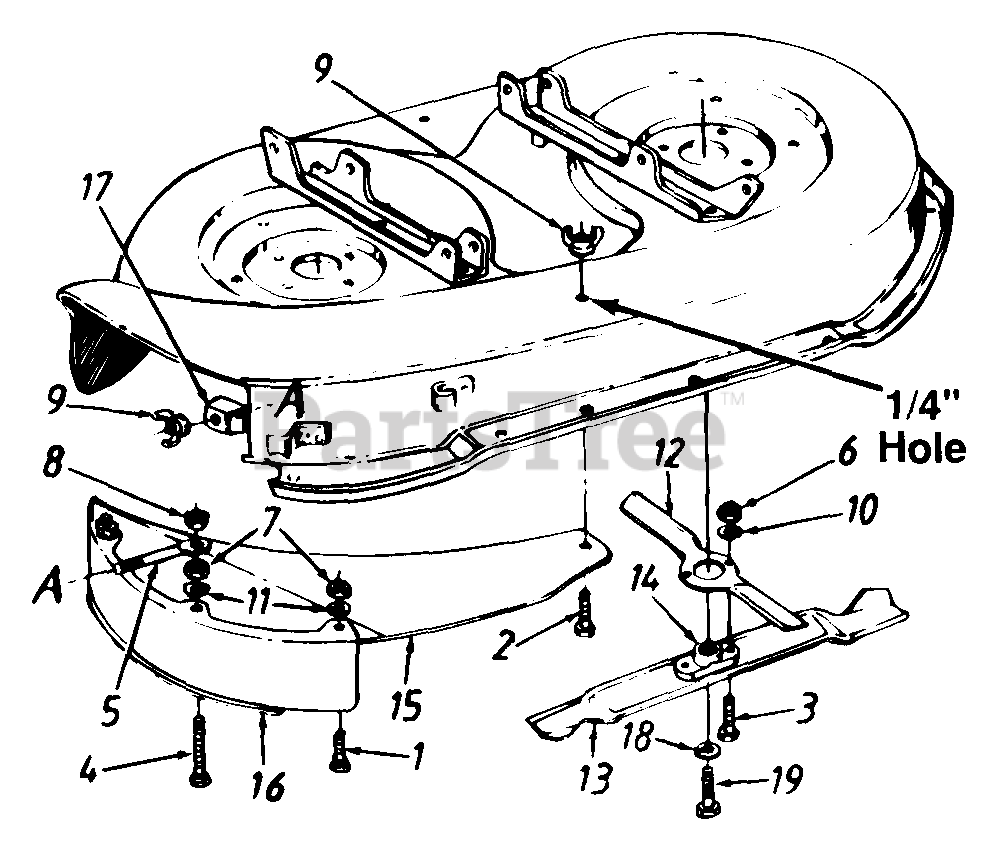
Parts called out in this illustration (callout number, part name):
1	Carriage Bolt 1/4-20 x .62" Lg.
2	Hex Bolt 1/4-20 x .62" Lg.
3	Hex Bolt 7/16-20 x 1.25" Lg. (Gr. 5)
4	Carriage Bolt 1/4-20 x 1" Lg.
5	Retaining Bolt
6	Hex Nut 7/16-20 Thd.
7	Hex Nut 1/4-20 Thd.
8	Hex L-Nut 1/4-20 Thd.
9	Wing Nut
10	L-Wash. 7/16" I.D.
11	L-Wash. 1/4" I.D.
12	Mulching Blade 12.5"
13	Mulching Blade 19.38"
13	Mulching Blade 21.2"
14	Blade Adapter
15	Top Mulching Baffle
16	Side Mulching Baffle
17	Locking Bracket
18	L-Wash. 3/8" I.D.
19	Hex Bolt 3/8-24 x 1" Lg.(Gr. 8)
